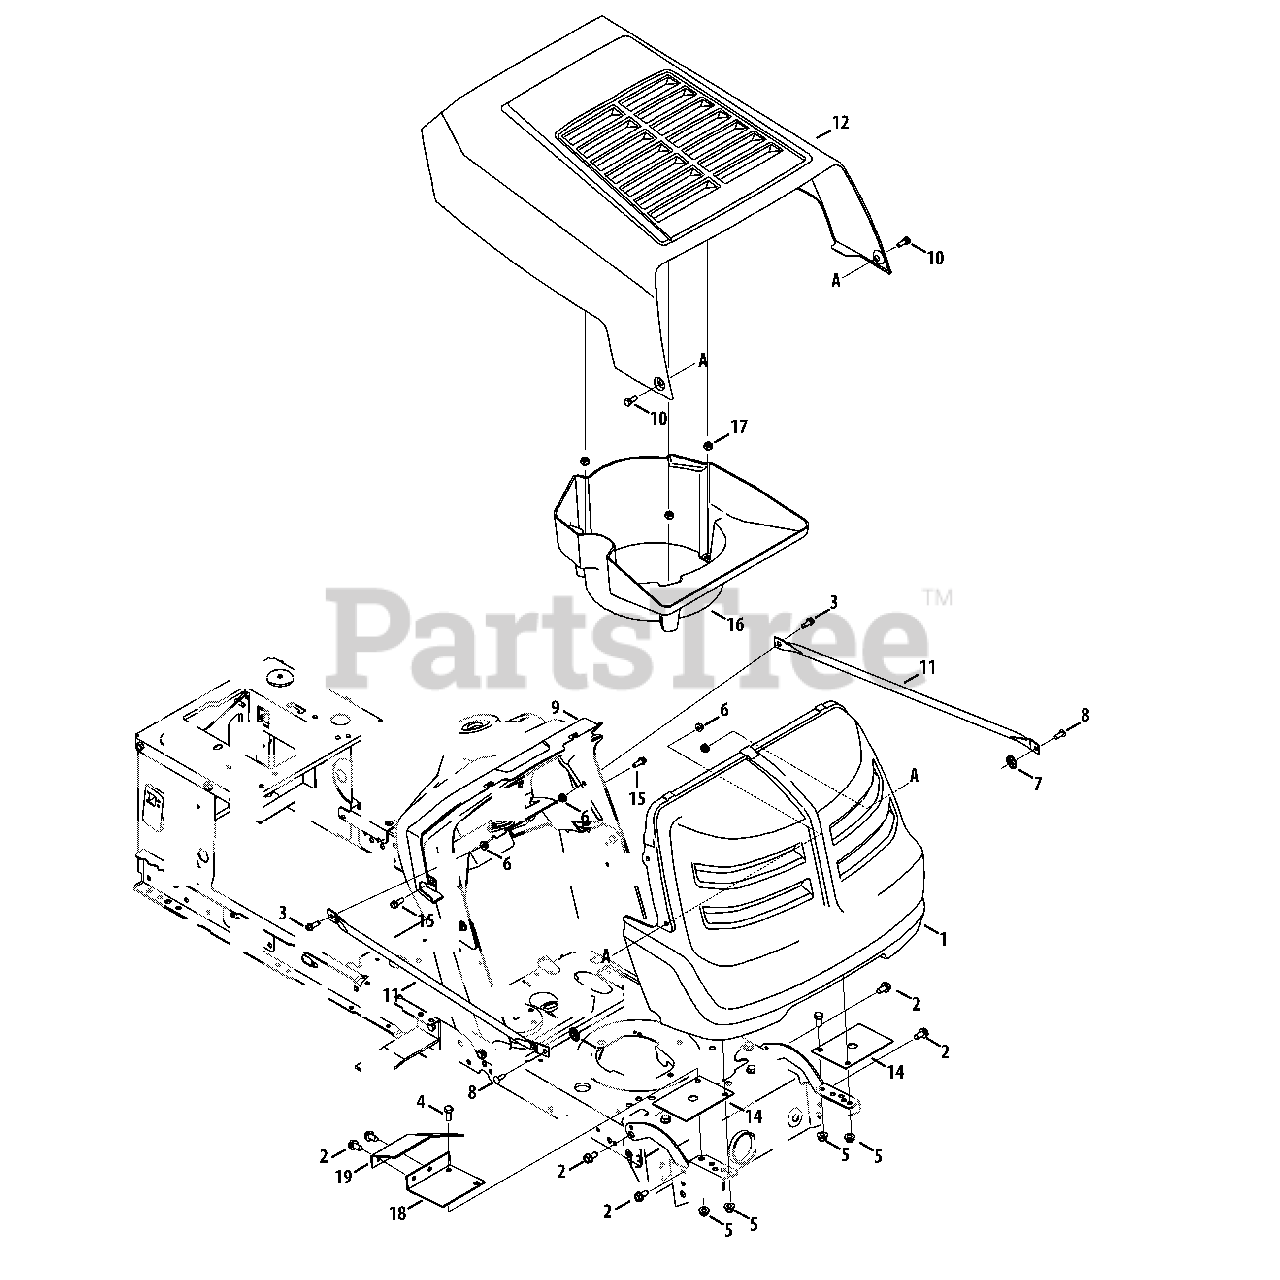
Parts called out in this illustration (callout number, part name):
1	Grill Assembly
2	Screw, Tap, 5/16-18, .750
3	Screw, Tap, 1/4-20, 0.750
4	Hex Screw, 5/16-18, .75
5	Flange Lock Nut, 5/16-18
6	Flange Lock Nut, 1/4-20
7	Nut, push-On, .25 Dia
8	Rivet, flat Head 1/4"
9	Collar, dash, 0/2 Style
10	Bolt, Shoulder, .375 X .125
11	Grill Support Rod
13	Front Pivot Support Bracket
14	Support Bracket
15	Screw, 1/4-15 x .750
16	Plenum
17	Spacer, .17 ID x .375 x .09
18	Heat Shield
19	Heat Shield
